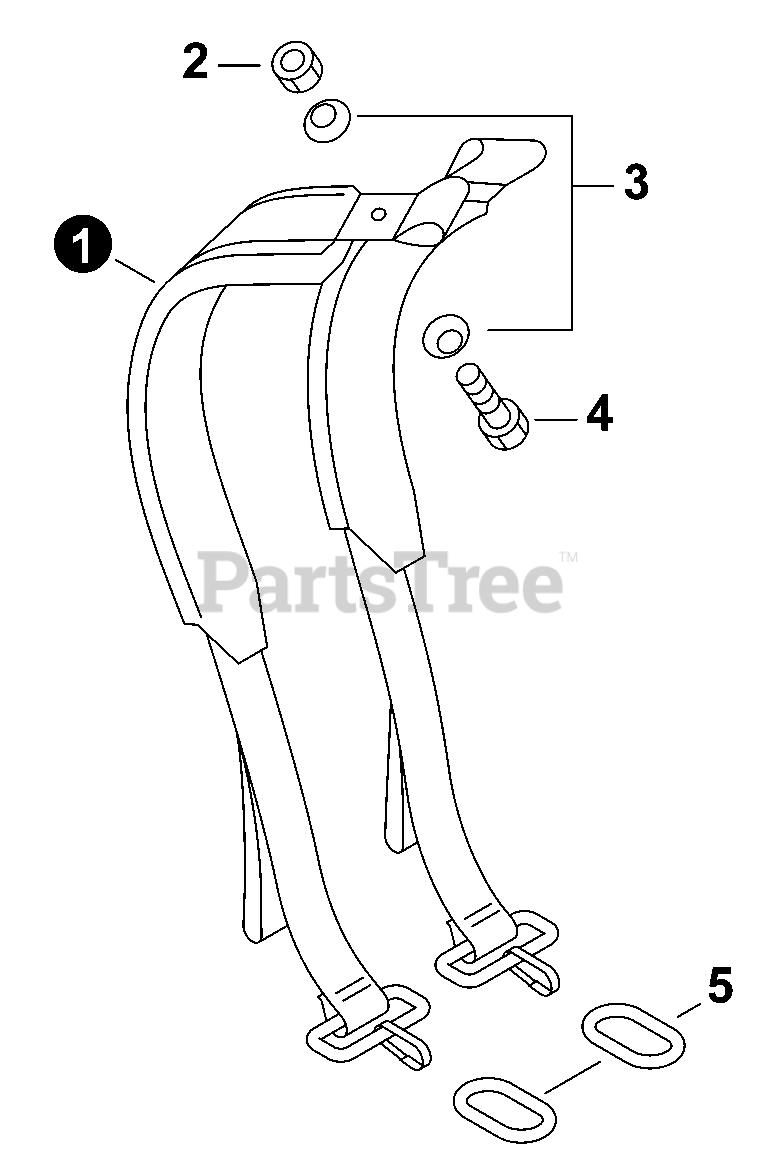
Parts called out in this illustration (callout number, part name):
1	HARNESS, BACKPACK
2	NUT, LOCK M5
4	SCREW 5x14
5	RING, HARNESS
